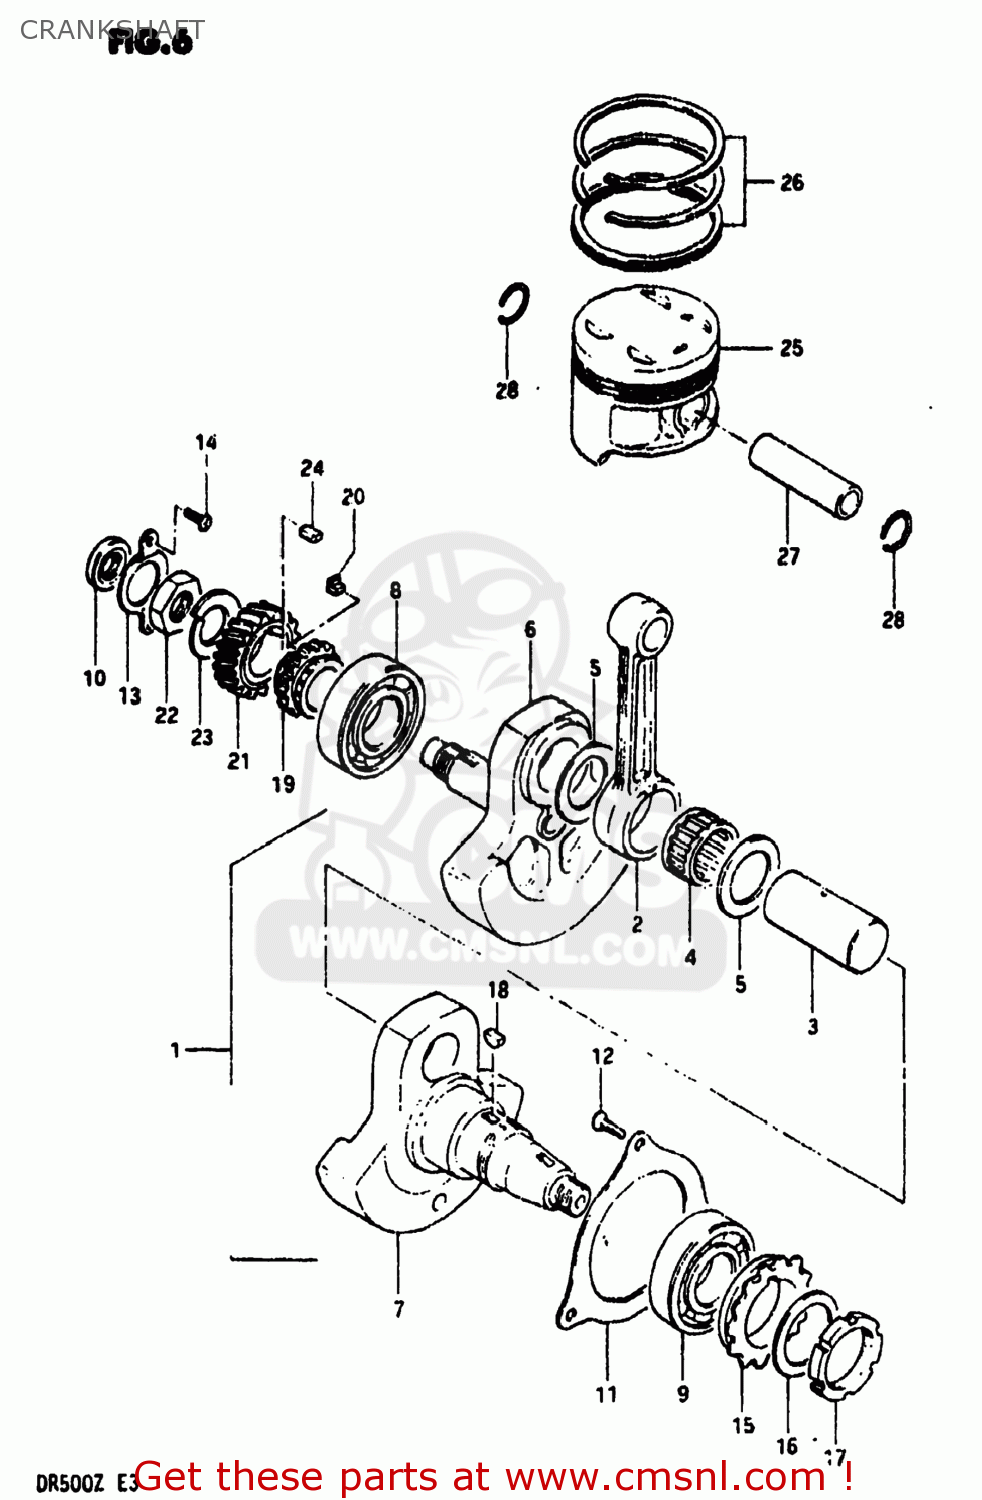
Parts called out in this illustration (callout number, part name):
1	CRANKSHAFT ASSEMBLY
2	ROD,CONNECTING
3	PIN,CRANK
4	BEARING(35X44X26)
5	WASHER(35X55X1)
6	CRANKSHAFT
7	CRANKSHAFT,LEFT
8	BEARING(35X80X21)
9	BEARING
10	SEAL,OIL(16X30X6)
11	RETAINER,CRANKSHAFT BEARING,L
12	SCREW
13	RETAINER,CRANKSHAFT BEARING,R
14	SCREW
15	SPROCKET,BALANCER DRIVE
16	WASHER
17	NUT,FLYWHEEL
18	KEY
19	SPROCKET,CAM CHAIN DRIVE
20	KEY,SPROCKET
21	GEAR,PRIMARY DRIVE
22	NUT (20MM)
23	WASHER
24	KEY
25	PISTON
26	RING SET,PISTON
27	PISTON PIN
28	RING,SNAP
